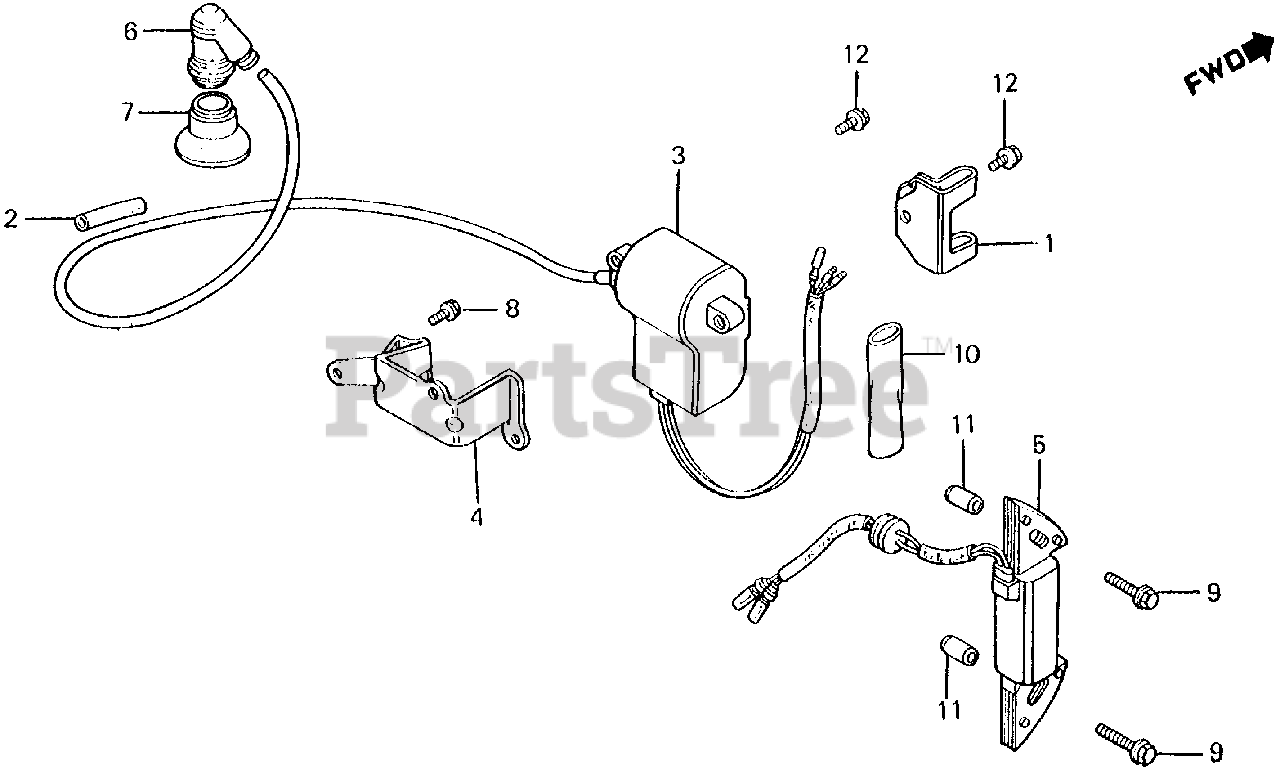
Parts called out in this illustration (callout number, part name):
1	CLIP, WIRE
2	TUBE, IGNITION RUBBER
3	MODULE, IGNITION CONTROL (CDI)
4	STAY, IGNITION CONTROL MODULE
5	COIL ASSY., EXCITER
6	CAP ASSY., NOISE SUPPRESSOR
7	SEAL, IGNITION
8	BOLT, FLANGE (6X12) (CT200)
9	BOLT, FLANGE (6X28)
10	TUBE, CORD
11	PIN A, DOWEL (8X14)
12	BOLT, FLANGE (6X12)
